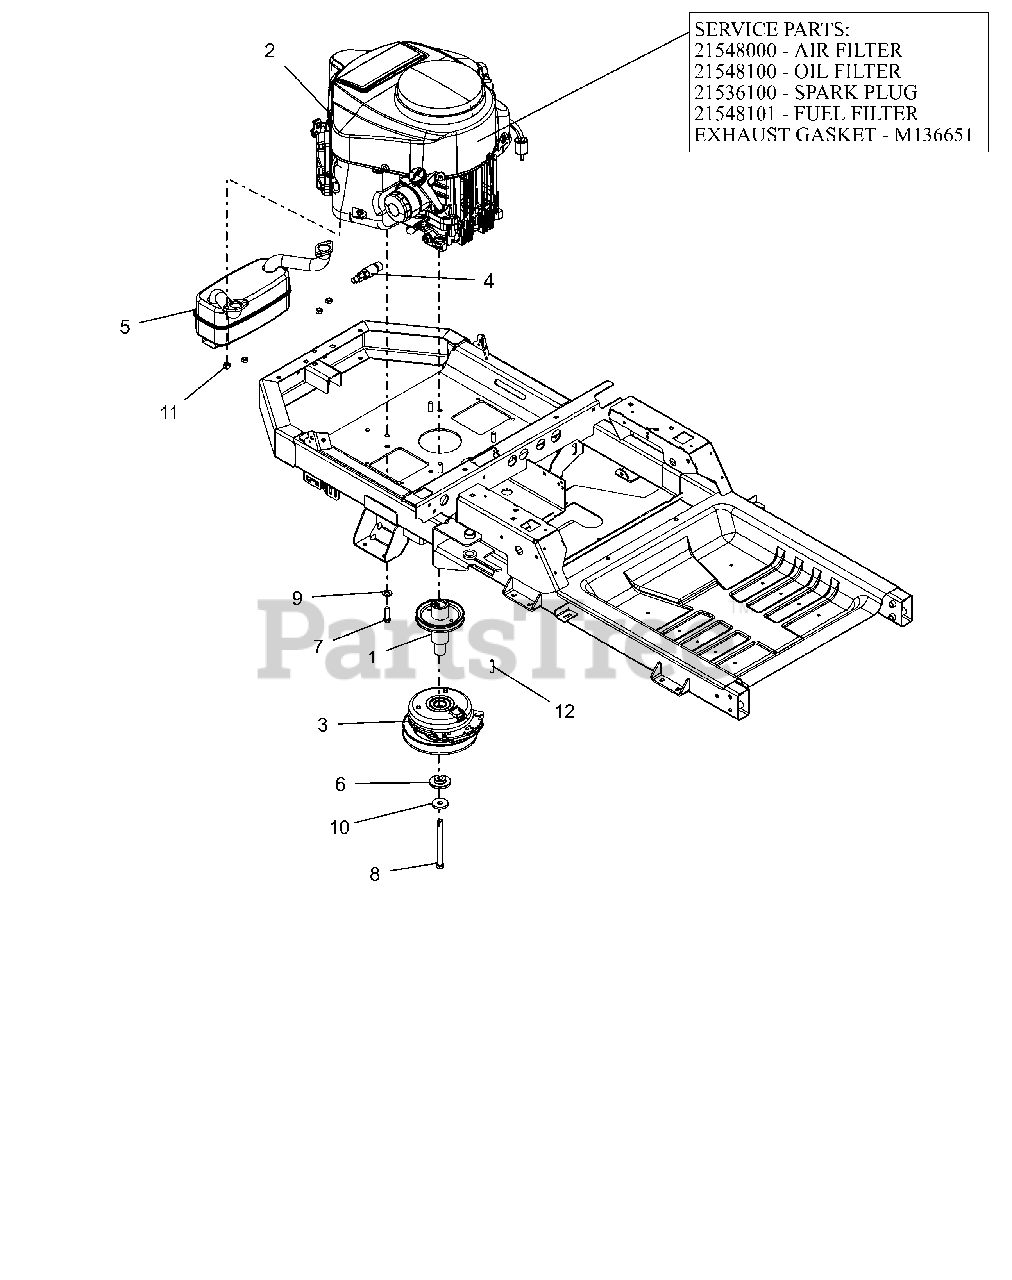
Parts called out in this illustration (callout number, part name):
1	WLDMT, DRIVE SHEAVE (LG XL)CZC
2	ENGINE, KAWASAKI FR730 24HP
2	AIR FILTER, KAWASAKI FR
2	OIL FILTER, KAWASAKI FR
2	PLUG, SPARK
2	FUEL FILTER-KAWASAKI FR
2	GASKET, MUFFLER #
3	CLUTCH,105FTLB MONOPOLE 6.83"
4	DRAIN, OIL M20X2.5
5	MUFFLER - KAWASAKI
6	BSHG-FLG .469X1.06X.574X2.0
7	BLT-HEX.38-16X1.25 G5YZ NYTORQ
8	BLT-HEX.438-20X5 GR8 YZ NYTORQ
9	WASHER, 3/8" SPRING DISC
10	WASHER, 7/16" SPRING DISK
11	NUT-LK-TOP M8-1.25 YWZC
12	KEY-SQ .25 X 1.25 X .25 SAE
